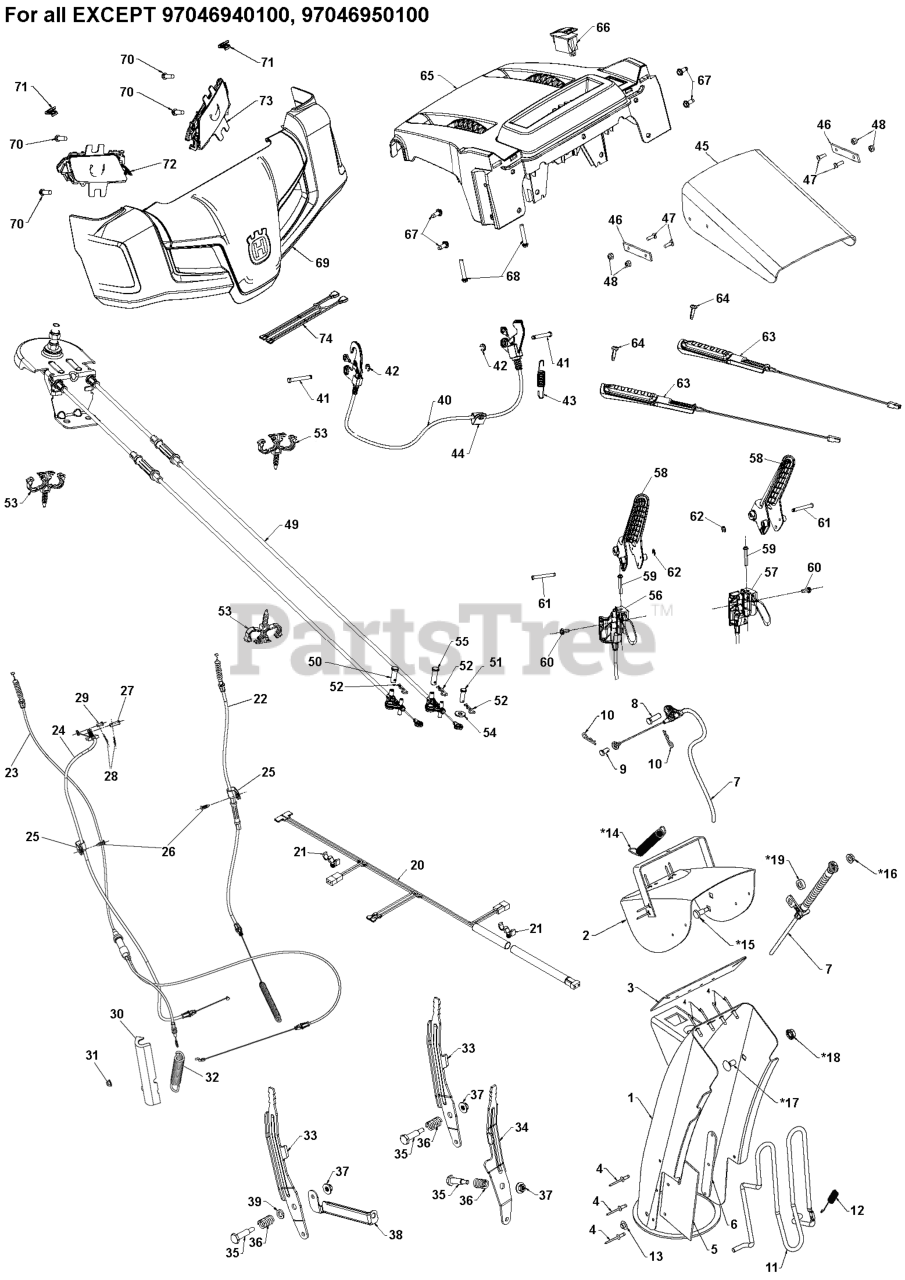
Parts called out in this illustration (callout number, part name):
1	ASM.CHUTE/DEFLECTOR.668
7	CABLE CONTROL.CHUTE.DEFLECTOR.
7	CABLE.CONTROL.CHUTE.DEFLEC
8	PIN CLEVIS 5/16X.875
9	PIN CLEVIS .25 X .31
10	HAIRPIN.SOFT.ZINC.059X1.125
11	ROD.GUARD.CHUTE (2 2)
11	GUARD ROD CHUTE GUARD SHORT CL
12	SPRING.CHUTE.GUARD
13	NUT
20	HARNESS WIRE.LIGHT AND GRIPS
22	Cables
22	CABLE DRIVE WITH ADJUSTER
23	CABLE IMPELLER
24	CABLE.CONTROL.SPEED.DSST.OPP
24	Cables
25	CLIP.CABLE.BLK
26	FASTENER.PUSH.O.250X0.783
27	PIN CLEVIS 5/16X.875
28	HAIRPIN.SOFT.ZINC.059X1.125
29	PIN CLEVIS .25 X .31
30	COVER AUGER CABLE
31	NUT HEXAGON FLANGE 5/16-18 ST
31	NUTNYLOK.FLRANGE.5/16-18
32	SPRING EXTENSION; AUGER EXTENS
33	LEVER.CONTROL.SPEED/DEFLEC.BLK
34	LEVER.CONTROL.CHUTE.ROTATON.BL
35	BOLT SHOULDER_HEX HD_1/4-20_3/
36	SPRING.COMPRESSION.82LBS
37	NUT HEX_LRG FLG_1_4-20_LOCK
38	BRACE.SUPPORT.SPEED.BLACK
39	WASHER.FLAT.625 X .375 NYLON
40	CABLE INTERLOCK CONTROL ACETAL
41	PIN.GROOVED
43	SPRING RETURN_INTERLOCK_DSST
44	CLIP.CABLE.BLK
45	SHIELD.DEFLECTOR.BLACK.SNOW
46	STRAP.DEFLECTOR.SHEILD
47	SCREW.MACHINE.8-32 X 1/2-BLK
48	NUT.HEX.NYLOCK
49	CABLE ASSY CONTROL
50	PIN CLEVIS 5/16X.875
51	PIN.CLEVIS
52	HAIRPIN.SOFT.ZINC.059X1.125
53	CLIP.CONDUIT.DOUBLE LOOP
54	WASHER FLAT_.250 X .625 X .06
55	PIN CLEVIS CLEVIS
56	CABLE.POWER STEERING.LHS
57	CABLE.POWER STEERING.RHS
58	LEVER ENGAGMENT
59	SCREW HEX_WASH_13-16 X 1.50_H
60	SCREW 14-20 X 5/8
61	PIN.GROOVED
63	GRIP.HANDLE.HEATED
64	SCREW.PAN.HD.TORX.1/4-20X.750
65	CONSOLE BASE MULTI CONTROL
66	SWITCH HEATED GRIP BLK
67	SCREW 14-20 X 5/8
68	SCREW HEX_WASH_13-16 X 1.50_H
69	COVER CONSOLE_ASM_HUSQVARNA
70	SCREW.HWH.13-16-5.8.BZP
71	CLIP PANEL ERGO 30603
72	LIGHT ASM.HUSQVARNA.RH
73	LIGHT ASM.HUSQVARNA.LH
74	HARNESS.WIRE.LIGHT.JUMPER
